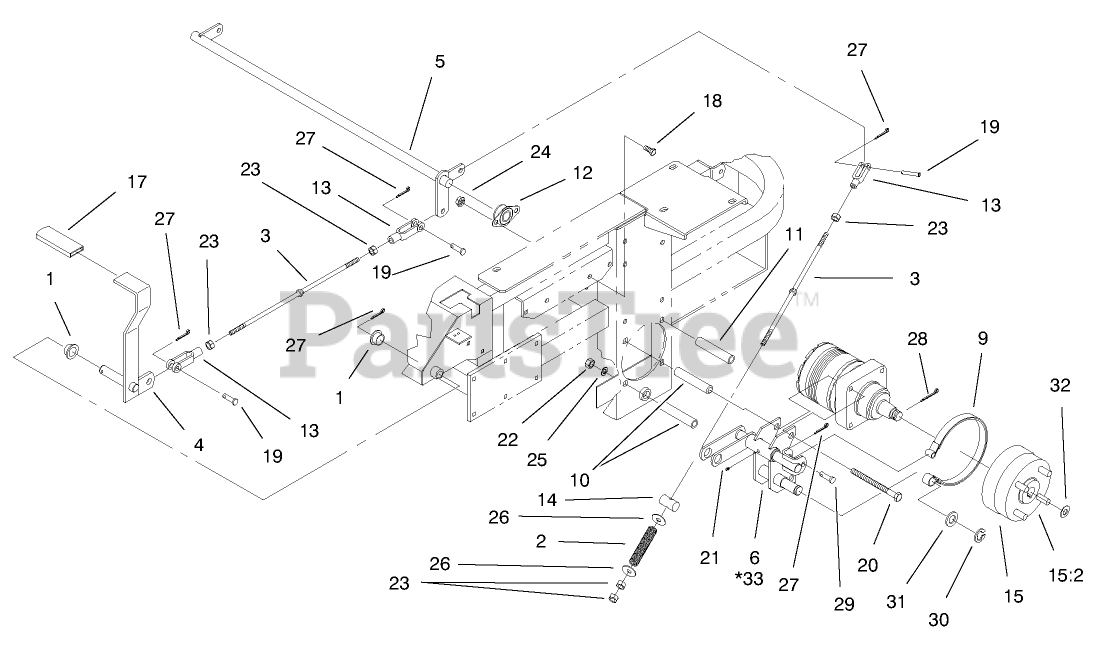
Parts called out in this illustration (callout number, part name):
1	Bearing
2	Spring-Brake
3	Rod-Brake
4	Lever-Brake
5	Shaft-Brake
6	Bracket-Brake LH
9	Band-Brake
10	Spacer
11	Spacer
12	Bearing-Side Flange
13	Yoke-Brake Linkage
14	Pin-Trunion
15	Hub And Drum ASM
15:2	Stud-Wheel
17	Grip-Brake Lever
18	SCREW-HH
19	Pin-Clevis
20	SCREW-HH
21	Fitting-Grease
22	NUT-HH
23	NUT-HEX
24	NUT-HHF, WHIZ
25	WASHER-LOCK
26	WASHER-FLAT
27	PIN-COTTER
28	Pin-Cotter
29	Pin-Clevis
30	Ring-Retaining
31	WASHER-FLAT
32	Spacer
